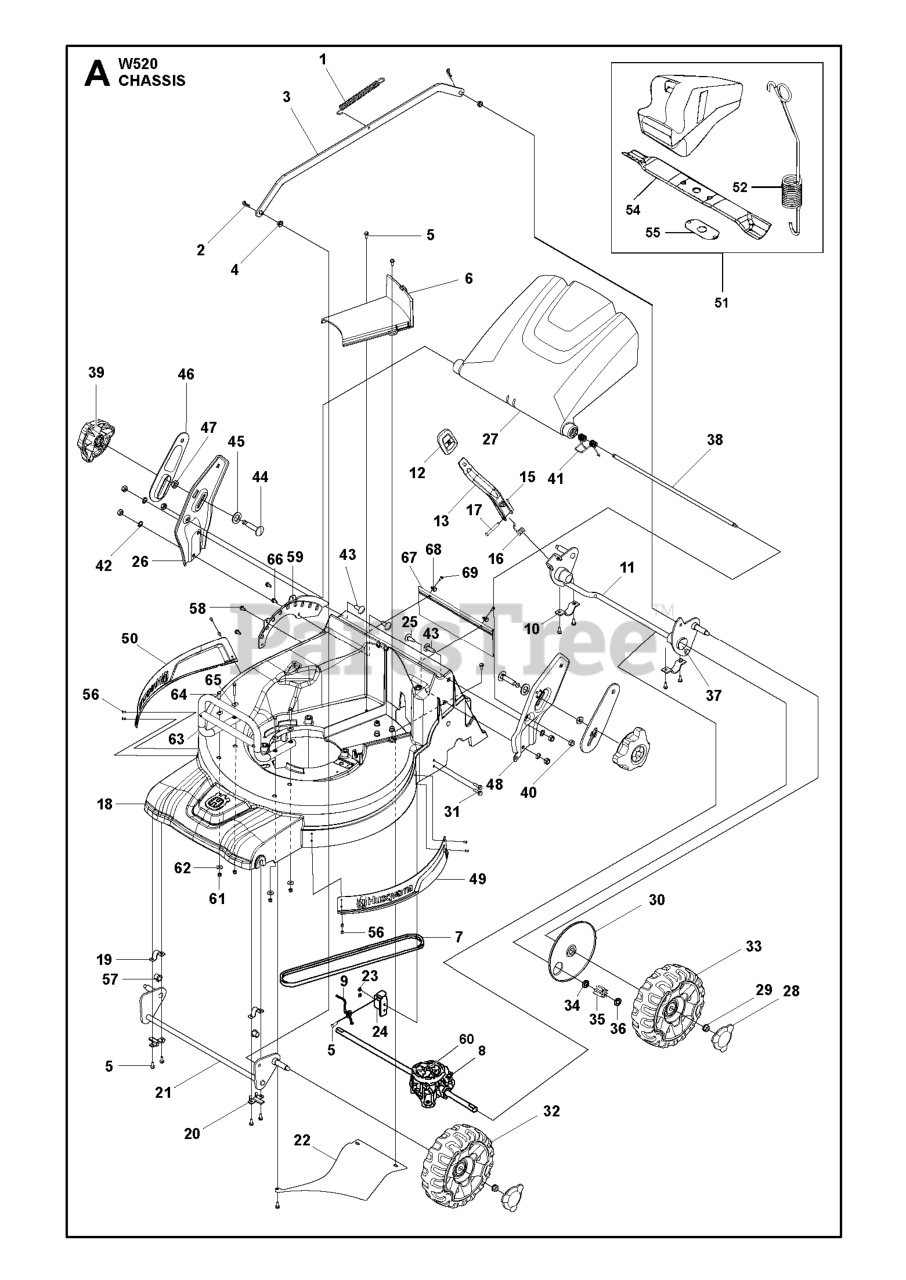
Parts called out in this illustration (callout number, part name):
1	SPRING HEIGHT ADJUSTER
7	Belts
31	SCREW M6S 5X20
37	Ball Bearings
40	LOCKNUT M8
41	SPRING 51 CAST
42	WASHER BRB 8.4X17
47	NUT ML6M M8
51	MULCH KIT
54	Blades
56	Rivet
60	TRANSMISSIONS
61	LOCKNUT M6
64	Hex Head Capscrew, M6 X 1.00 X 40MM
69	SCREW ITXPANTT M5X10 ZPB (A00
